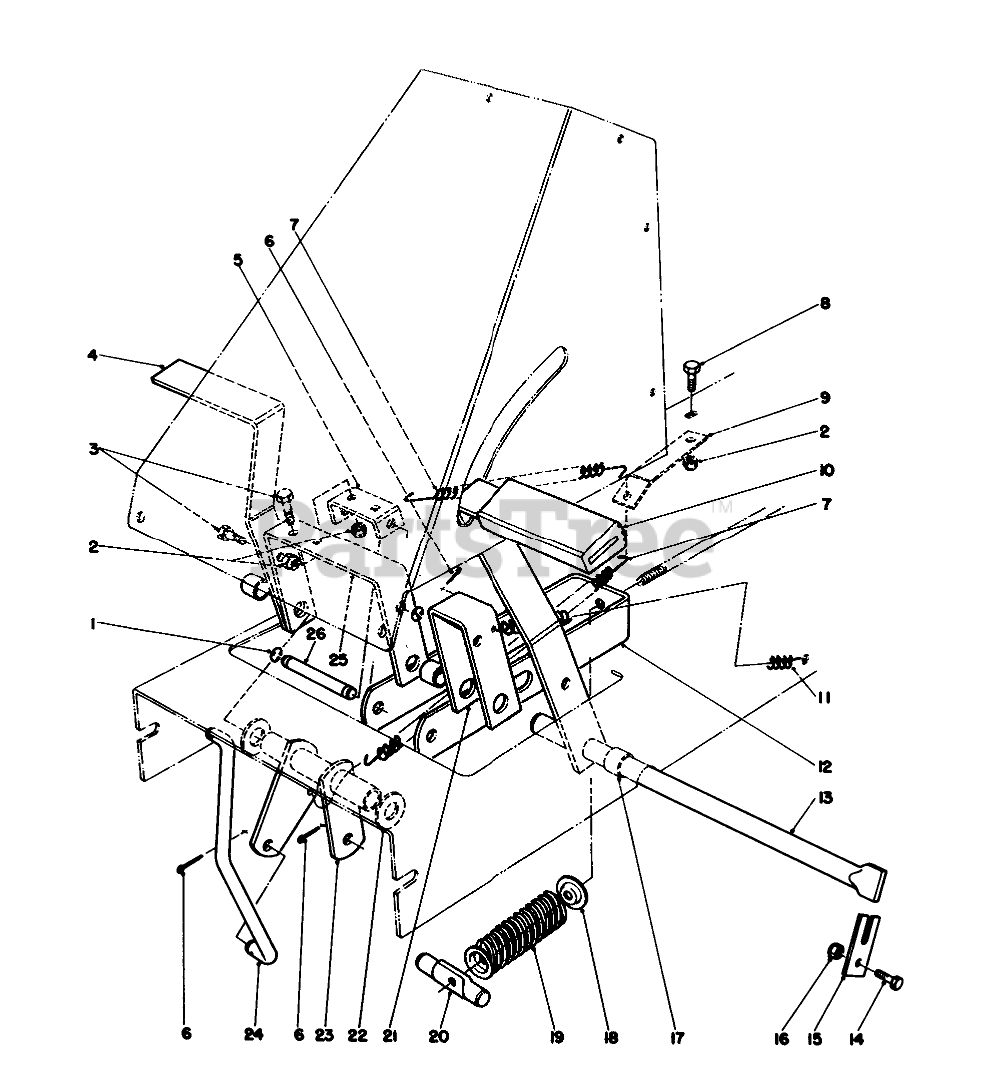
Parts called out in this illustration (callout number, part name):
1	E-RING
2	NUT-LOCK, NI
3	SCREW-HH
4	Pedal
5	Bracket-Brake
6	PIN-COTTER
7	TRACTION SPRING
8	SCREW-HH
9	Bracket-Spring Retaining
10	Pad-Foot Pedal
11	SPRING-EXTENSION
12	Bracket-Engagement
13	SHAFT-PEDAL PIVOT
14	SCREW-HH
15	RETAINER-SHAFT
16	NUT-LOCK, CONE
17	SPACER-PEDAL
18	RETAINER-SPR. TOP
19	SPRING-COMPRESSION
20	SHAFT-DECK ADJ.
21	Bracket-Clutch Pedal
22	WASHER-FLAT
23	Tube-Pivot
24	Arm-Engagement
25	Bracket-Brake Pedal
26	Pin-Clevis
